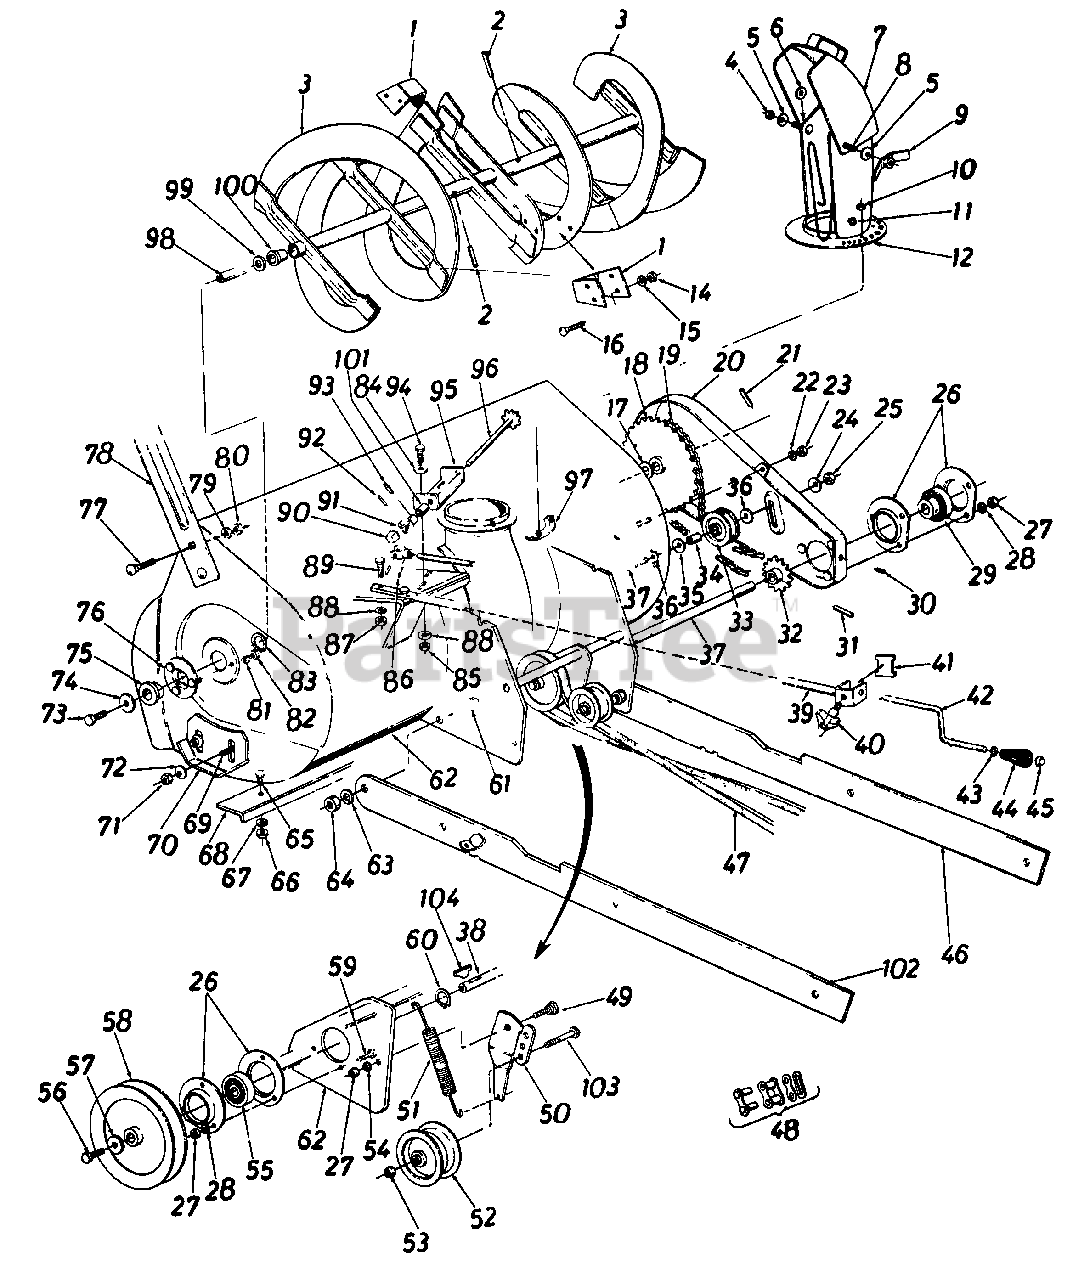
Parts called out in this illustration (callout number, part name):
1	Spiral Plate
2	Spring Pin Spir. 5/16 x 1.75" Lg.
3	Spiral Ass'y.
4	Hex Cent. L-Nut 5/16-18 Thd.
7	Top Chute Ass'y.
8	Car. Bolt 5/16-18 x .62" Lg.
9	Chute Wing Ass'y.
10	HexCent. L-Nut1/4-20Thd.
11	Push Cap.188" Dia. Rod
12	Chute Ass'y.
14	Hex Nut 5/16-18Thd.*
15	L-Wash. 5/16" Scr.*
16	Car. Bolt 5/16-18x .62" Lg.*
18	Sprocket Hub Ass'y.-40 Teeth
19	#420 Chain x 1/2" Pitch-77 Links
20	Chain Guard Ass'y.
21	Spring Pin Spir.-5/16
22	L-Wash. 5/16" Scr.*
23	Hex Nut 5/16-18 Thd.*
25	Hex Ins. L-Nut3/8-16 Thd.
26	Bearing Housing
27	Hex Nut 5/16-18 Thd.*
28	L-Wash. 5/16" Scr.*
29	Self Aligning Brg. w/ Set Scr.
31	Spring Pin Spir.-5/16x1.75
32	14 Teeth Sprocket Ass'y.
33	1.875" Dia. Flat Idler
34	Idler Spacer
35	F I-Wash .
37	Hex Scr. 3/8-16x2.00" Lg.*
39	Crank Support Tubing Ass'y.
40	Hand Knob 5/16-18 Thd.
41	Chute Crank Brkt.
42	Chute Crank
43	Fl-Wash.
44	Knob-Black 3/8" Dia. Hole
45	Push Nut 3/8" Rod
46	Linkage Arm Ass'y.
47	"V"-Belt 1/2"x85" Lg. (Kevlar)
48	Master Link for #420 Chain
49	Shoulder Scr.
50	Idler Brkt. Ass'y.
51	Extension Spring
52	Fl. Idler with Flange
53	Hex Ins. Jam Nut 3/8-16 Thd.
54	L-Wash. 5/16" Scr.*
55	Self Aligning Brg.
56	Hex Scr. 5/16-18x .62" Lg.
58	5.50 O.D. x 5/8 Pulley
59	Hex Sems Scr. 5/16-18 x .75"
60	Snap Ring for .75 Dia. Shaft
61	Hex Scr. 1/2-13x1.25" Lg.*
62	Spiral Housing Ass'y.
63	L-Wash. 1/2" Scr.*
64	Hex Nut 1/2-13 Thd.*
65	Car. Bolt 5/16-18 x .62" Lg.*
66	Hex Nut 5/16-18 Thd.*
67	L-Wash. 5/16" Scr.*
69	Car. Bolt3/8-16x .75" Lg.*
73	Hex Scr. 5/16-18x .62" Lg.
75	Flange Brg. with Flats
76	Brg. Housing Ass'y.
77	Car. Bolt 5/16-18 x .62" Lg.
78	Guide Blade
79	L-Wash. 5/16" Scr.*
80	Hex Nut 5/16-18 Thd.*
81	L-Wash. 5/16" Scr.*
82	Hex Nut 5/16-18 Thd.*
83	Snap Ring for 1.50" Dia. Shaft
85	Hex Nut 5/16-18 Thd.*
86	Cotter Pin 3/32 x 1.00" Lg.*
87	Hex Nut 5/16-18 Thd.*
88	L-Wash. 5/16" Scr.*
89	HexScr.5/16-18 x 1.50" Lg.
91	Joint Brkt. Ass'y.
92	Spring Pin Roll 3/16" x .81" Lg.*
93	Spring Pin Roll 1/8x .75" Lg.*
94	Hex Scr. 5/16-18x .75" Lg.*
95	Chute Brkt.
96	Sprocket Shaft Ass'y.
97	Chute Flange Keeper Ass'y.
100	Plastic Bushing
101	Spacer .380 I.D. x .630 O.D. x .565
102	Linkage Arm Ass'y.-R. H.
103	Hex Bolt 3/8-16 x 1.75" Lg.*
104	#61 Hi-Pro Key
